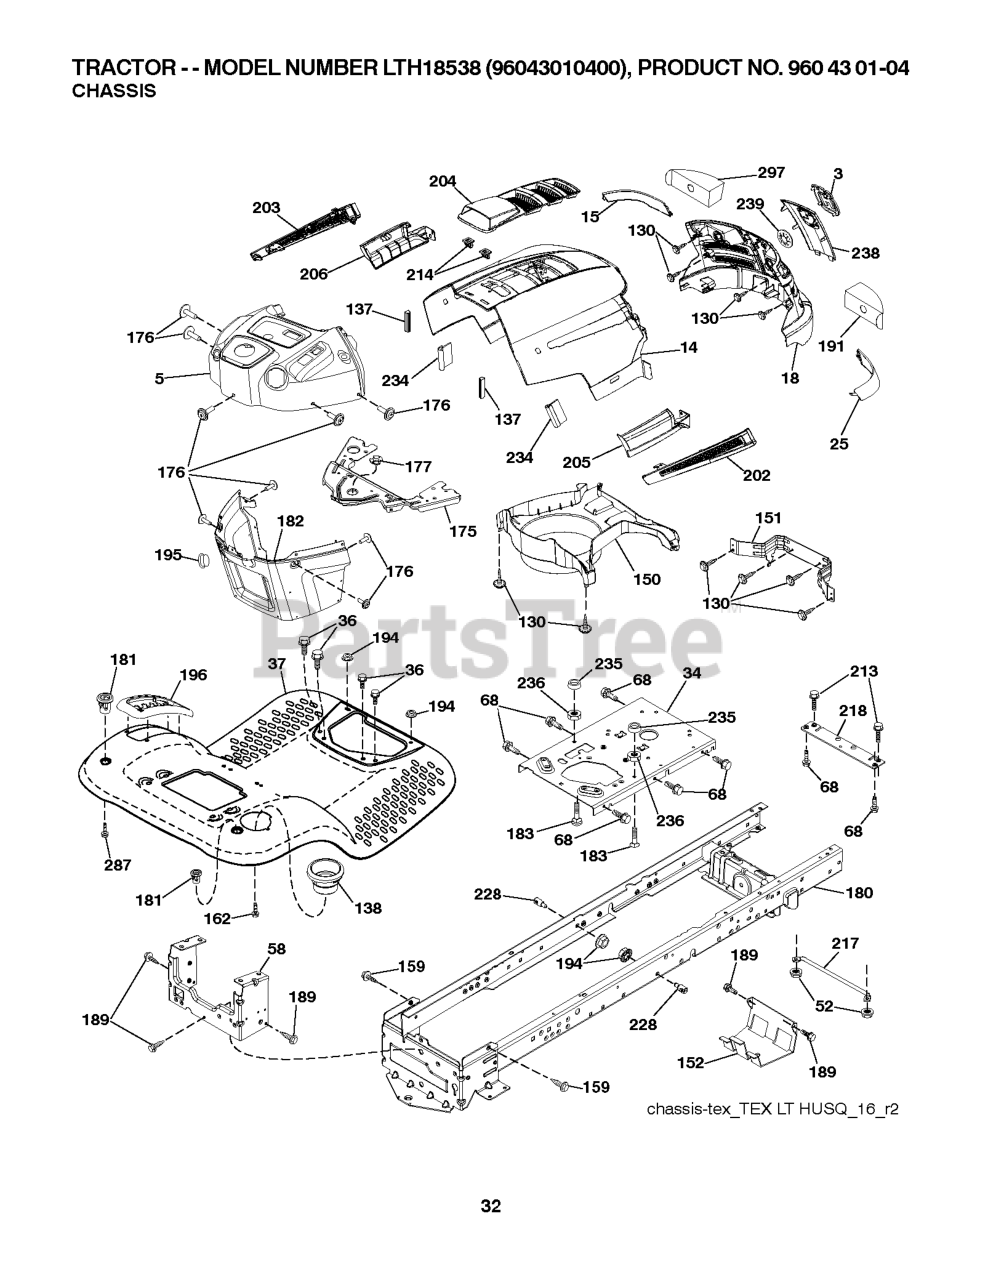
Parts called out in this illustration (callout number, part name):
3	RP LOGO
5	DASH
14	HOOD
15	LENS.HUSQVARNA LT.LH
18	GRILLE.SVC.HUSQVARNA.LT.GREY
25	LENS.HUSQVARNA LT.RH
34	PLATE.ENGINE.WELDED.CHASSIS
36	SCREW 5/16"
37	RP FENDER.TLT.FS.W/CPH.422
52	LOCKNUT
58	DRAWBAR UPPER 2PC SMALL FENDER
68	Screw 5/16-18 x 1/2 Hex, Self Tapping 5/16-18 x 1/2
130	SCREW.#10 X 0.750.BOS
137	BUMPER DASH
138	CUPHOLDER.TL.TEX.418
151	BRACKET PIVOT
152	SHIELD.BROWNING.W/TEX
159	SCREW, 3/8-16X3/4
162	SCREW.HI-LO.CONSOLE
175	CROSSMEMBER
176	SCREW.#10-24X5/8.RN.QU
177	BUSHING STEERING
180	CHASS.WLDMNT.TL.12GA/2P.48/54
181	BUSHING.MNT.FEND.CRGO.
182	DASH.LOWER.PREDATOR LT
183	BOLT.5/16-18X1-1/4 FULL THD
189	SCREW
191	INSERT.REFLECTIVE.RH.
194	NUT LOCK HEX FLANGE 5/16-18
195	PLUG DASH
196	RP CONSOLE.ASM.DECKLFT.GR/RBT.
202	VENT SIDE HOOD LH
203	VENT SIDE HOOD RH
204	VENT TOP HOOD
205	SKIRT SIDE RH
206	SKIRT SIDE LH
213	BOLT
214	CLIP.RETAINER.TINNER.
217	ROD.PIVOT.HOOD
218	X-PIECE.HOOD.STOP.NON/
228	STUD.FASTNER.W/ANTI-ROTATE
234	BUMPER.HOOD.TEX.HUSQVARNA
235	SPACER FENDER
236	NUT.CENTERLOCK.5/16-
238	TRIM
287	SCREW 1/4X20
297	INSERT REFLECTIVE
